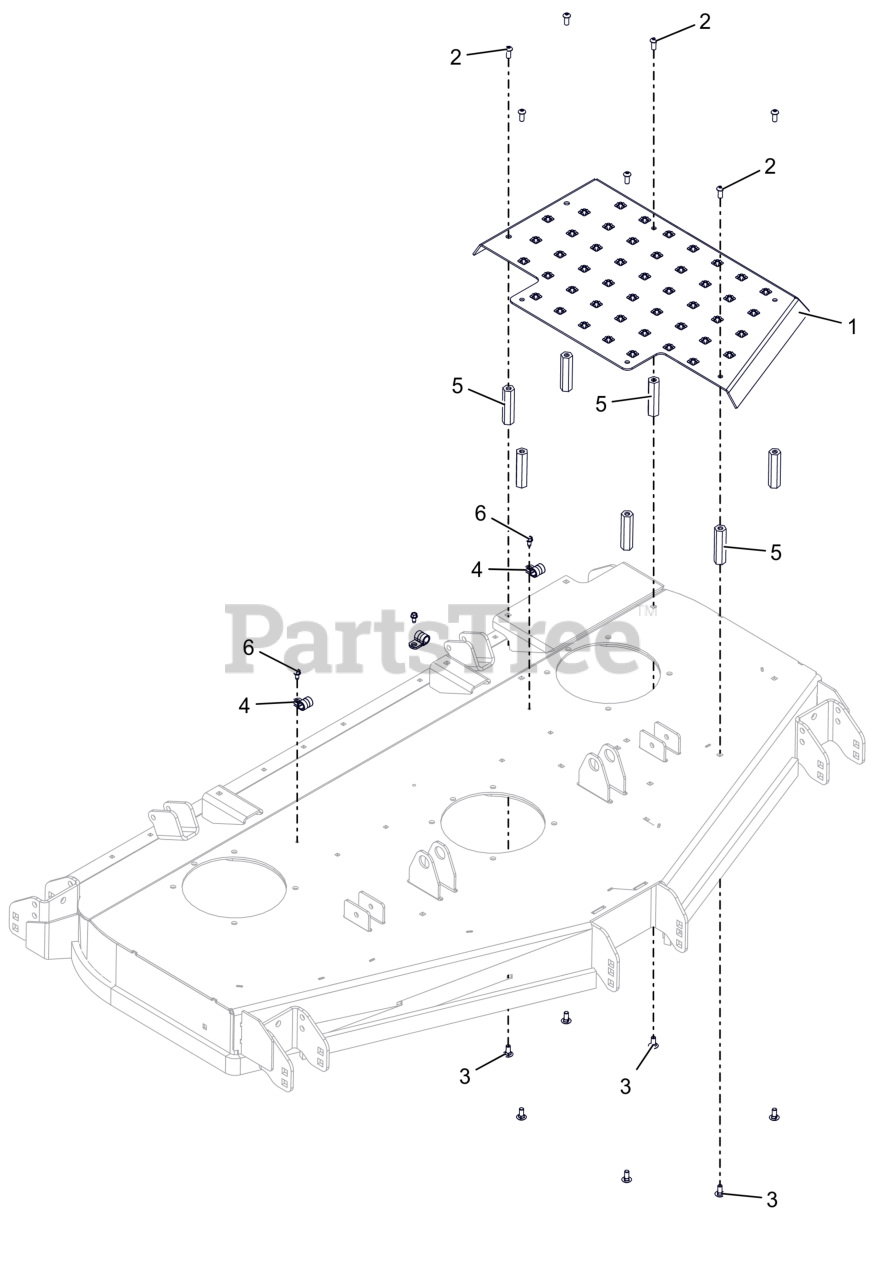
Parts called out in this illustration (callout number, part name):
1	PLATFORM, WLDMT 60 RD DECK STEP (ORANGE)
2	SCR-SKH .31-18X.75 BTNHD YWZC
3	BLT, RHSN .31-18X.75 G5 ZCC LT
4	CLAMP, CUSHIONED STEEL
5	NUT, COUPLING .31-18 X 3.00
6	SCR-TAP .25-20X.50 HWH ZCC
